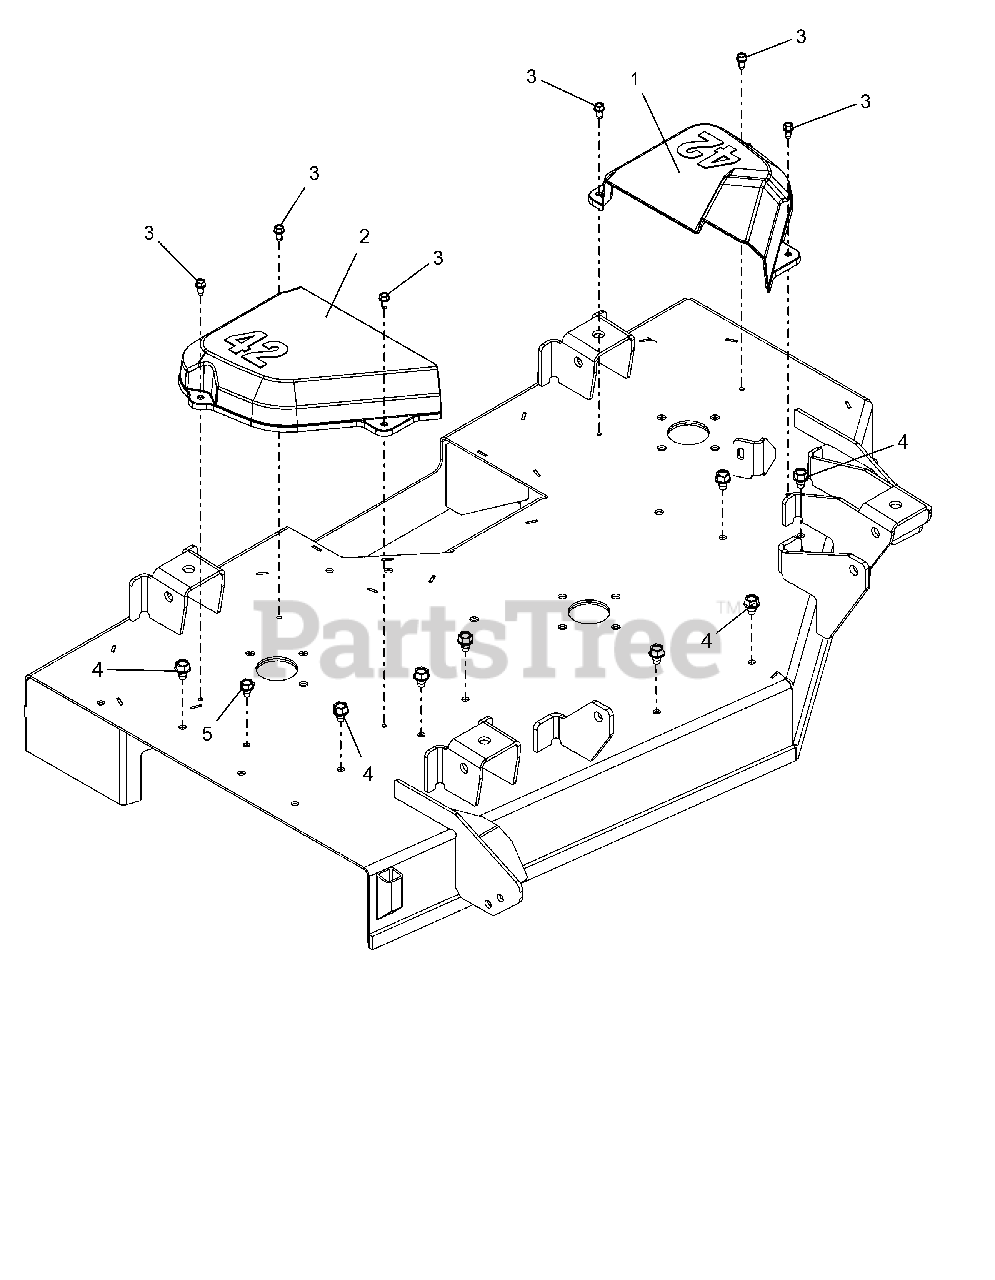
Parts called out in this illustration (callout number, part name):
1	COVER, BELT 42" LH
2	COVER, BELT 42" RH
3	SCR-TAP .25-20X.50 HWH ZCC
4	SCR,TAP .375-16X.50 HWH TR ZCC
5	SCR,TAP .312-18X.50 HWH TR ZCC
